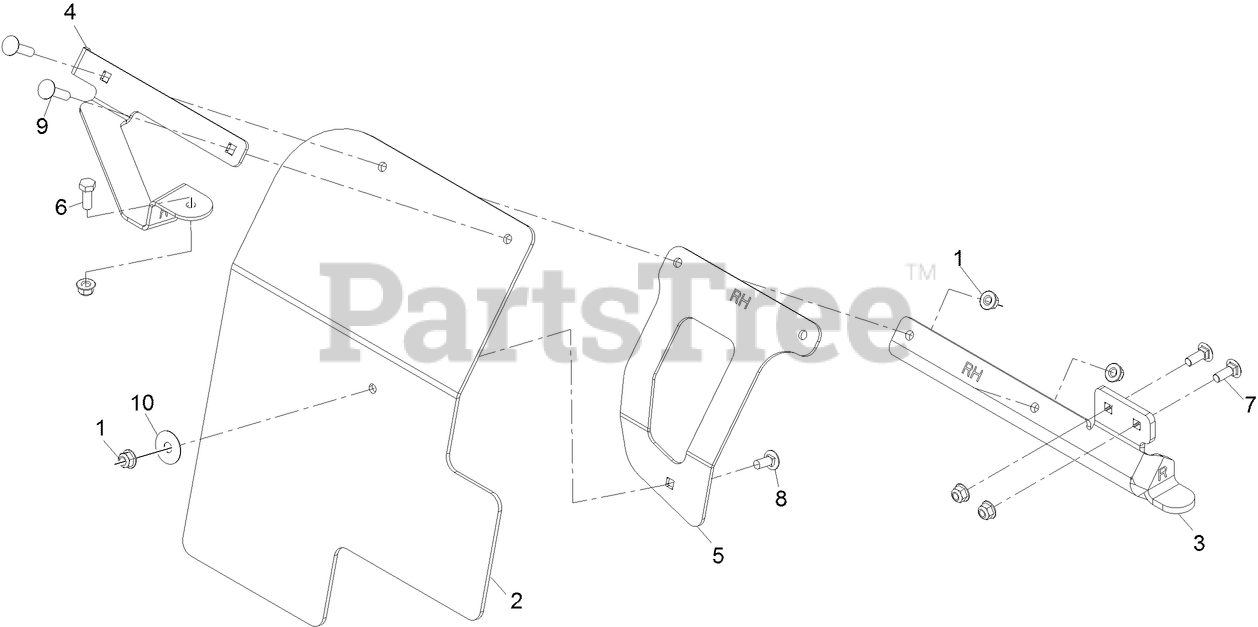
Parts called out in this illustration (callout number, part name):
1	NUT-HF, NI
2	RH MUD FLAP
3	BRACKET, RH MUD FLAP
4	FORWARD SUPPORT, RH MUD FLAP
5	SUPPORT, RH MUD FLAP
6	SCREW-HH
7	SCREW-CARR
8	SCREW-CARR
9	Bolt-Carriage 5/16-18 X 1 1/4
10	WASHER-PLAIN
